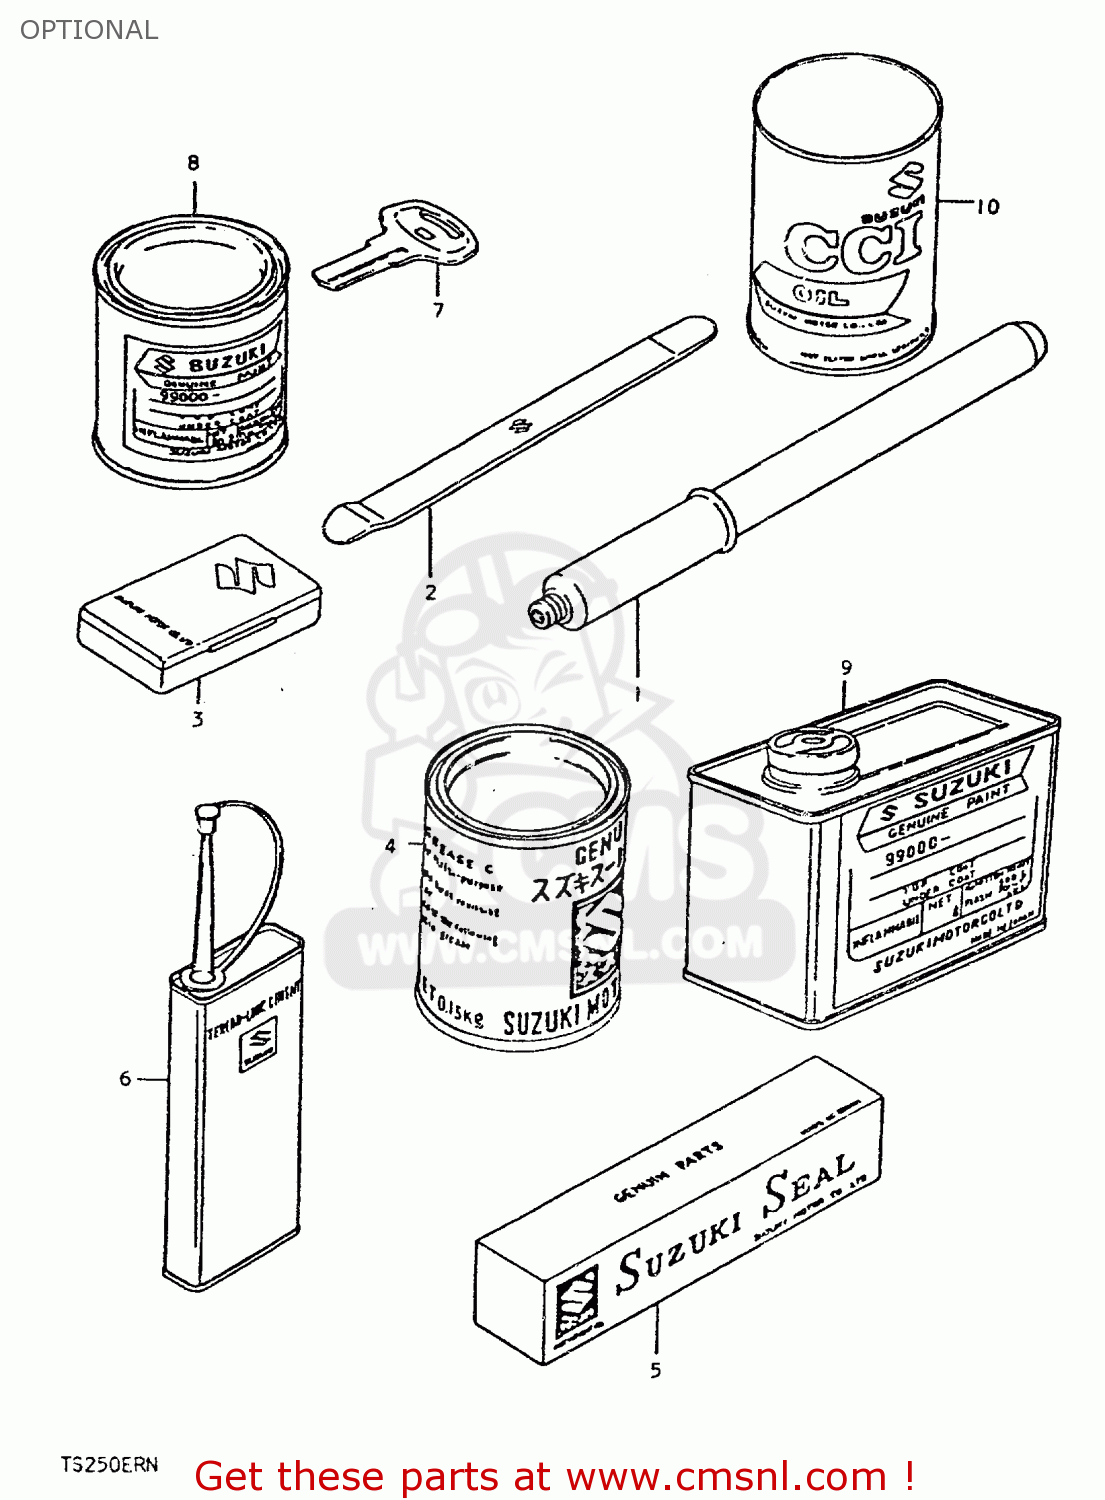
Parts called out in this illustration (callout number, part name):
1	INFLATOR, AIR
2	LEVER,TIRE
3	TUBE REPARING TOOL
4	GREASE(C)EP2 LITHIUM 150G
5	GASKET, LIQUID
6	THREAD LOCK NO.1401 CLEAR 200G
7	KEY,BLANK
8	PAINT,BLACK
9	PAINT (BLACK)
10	CCI OIL
